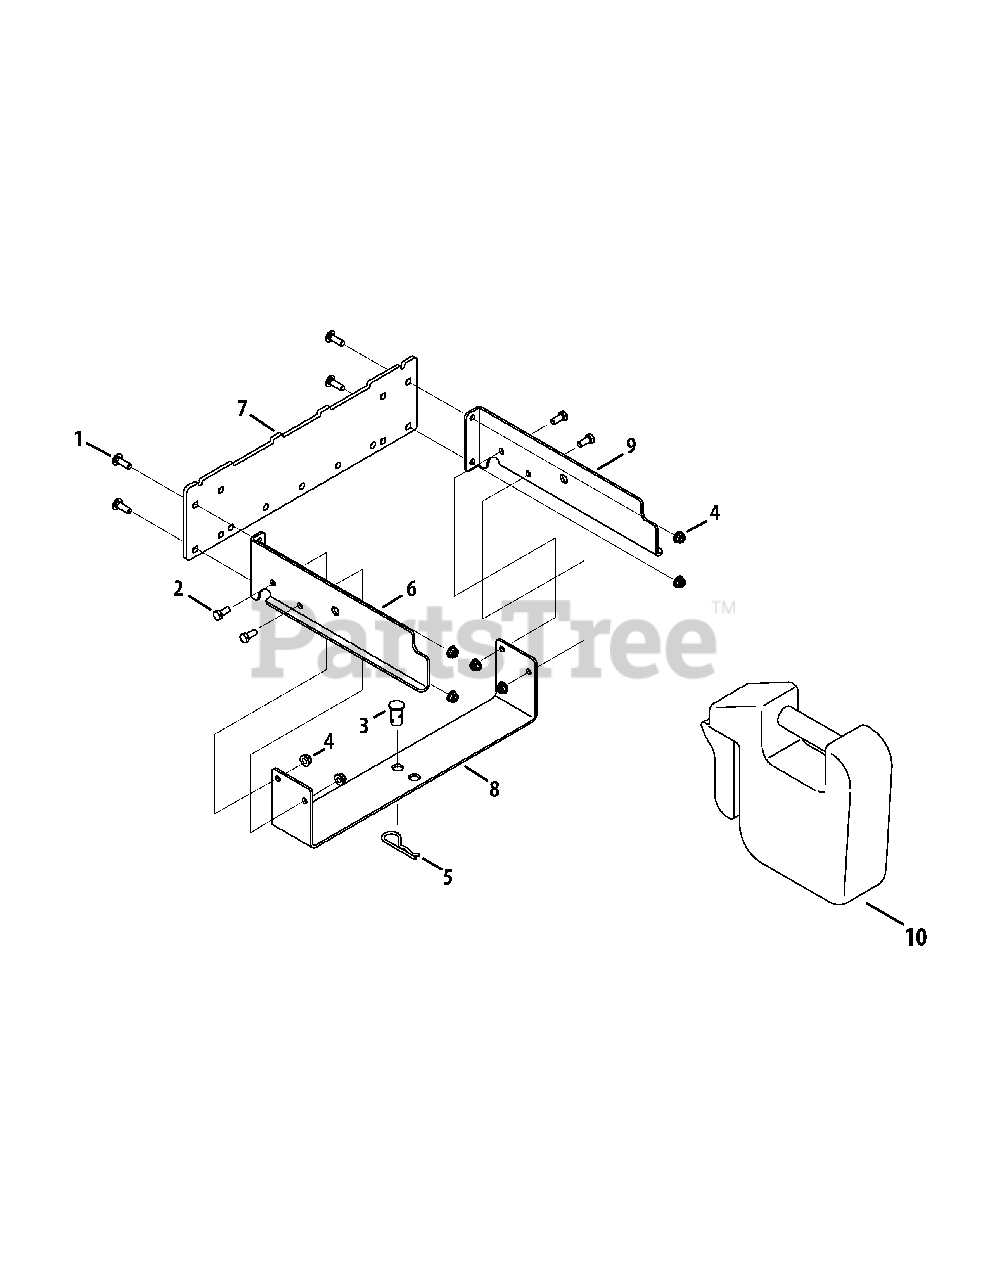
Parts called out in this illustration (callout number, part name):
1	Carriage Screw, 5/16-18 x 1.00"
2	Hex Head Screw, 5/16-18 x .75"
3	Clevis Pin, .62" Dia.
4	Flange Lock Nut, 5/16-18
5	Internal Cotter Pin, .148 x 3.00
6	Hitch Bracket, RH
7	Rear Attachment Bracket
8	Universal Bracket Support
9	Hitch Bracket, LH
10	Suitcase Weight, 45 lb.
